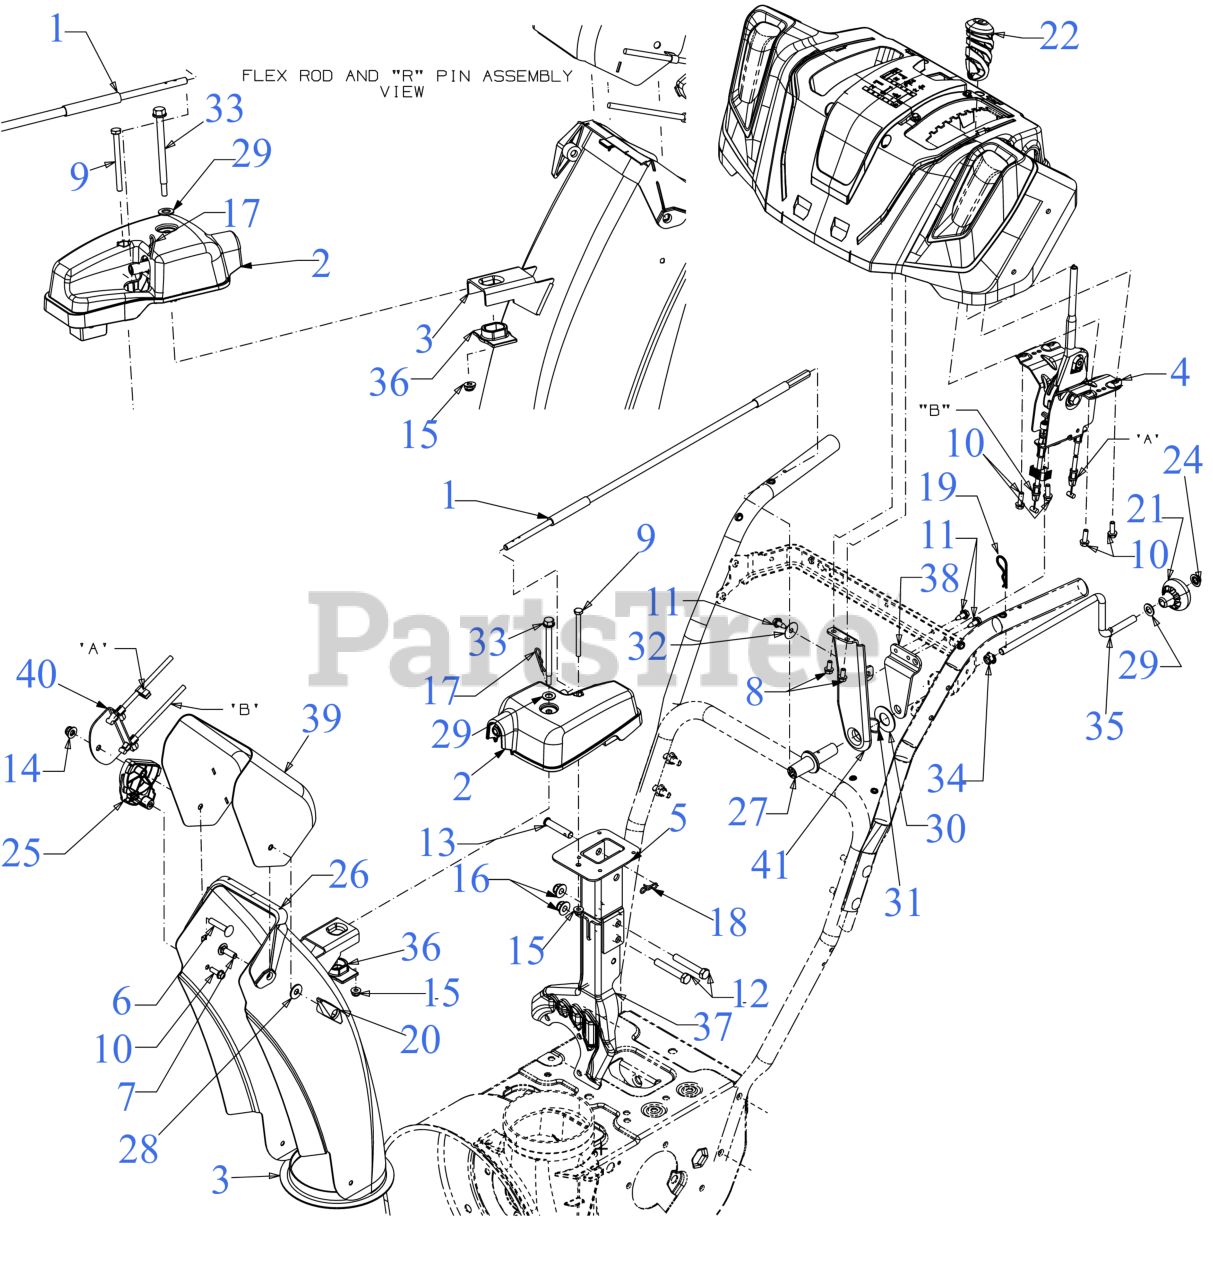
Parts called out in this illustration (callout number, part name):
1	CHUTE CONTROL
2	2-WAY CHUTE ROTATE GEARBOX
4	2-WAY STEEL CHUTE CONTROL ASSEMBLY
5	EXTENSION CHUTE MAST
6	CARRIAGE BOLT 5/16-18 x 1.50
7	CARRIAGE BOLT 5/16-18 x 1.00
8	HEX SCREW 1/4-15 x .50
9	SCREW 1/4-20 x 3.0 GR5
10	SCREW 1/4-15 x .750
11	SCREW 1/4-20X.625
12	SCREW 3/8-16 x 2.25 GR5
13	CLEVIS PIN 3/8 x 1.87
14	FLANGE LOCK NUT 5/16-18
15	FLANGE LOCK NUT
17	INTERNAL COTTER PIN
18	BOW TIE COTTER PIN 1/4-5/16
19	INTERNAL COTTER PIN
20	WING KNOB NUT
21	SHIFT KNOB
22	PTO HANDLE GRIP .355 ID
25	CHUTE TILT GUIDE
26	UPPER CHUTE ADAPTER
27	CHUTE ROD COUPLER
28	FLAT WASHER
29	FLAT WASHER
30	FLAT WASHER
31	WAVE WASHER .785X1.00X.012
32	FLAT WASHER
33	SHOULDER SCREW
34	BUSHING .380 ID
35	CHUTE CRANK (POWDER BLACK)
36	HELICAL GEAR CHUTE ADAPTER
38	ROD SUPPORT BRACKET
